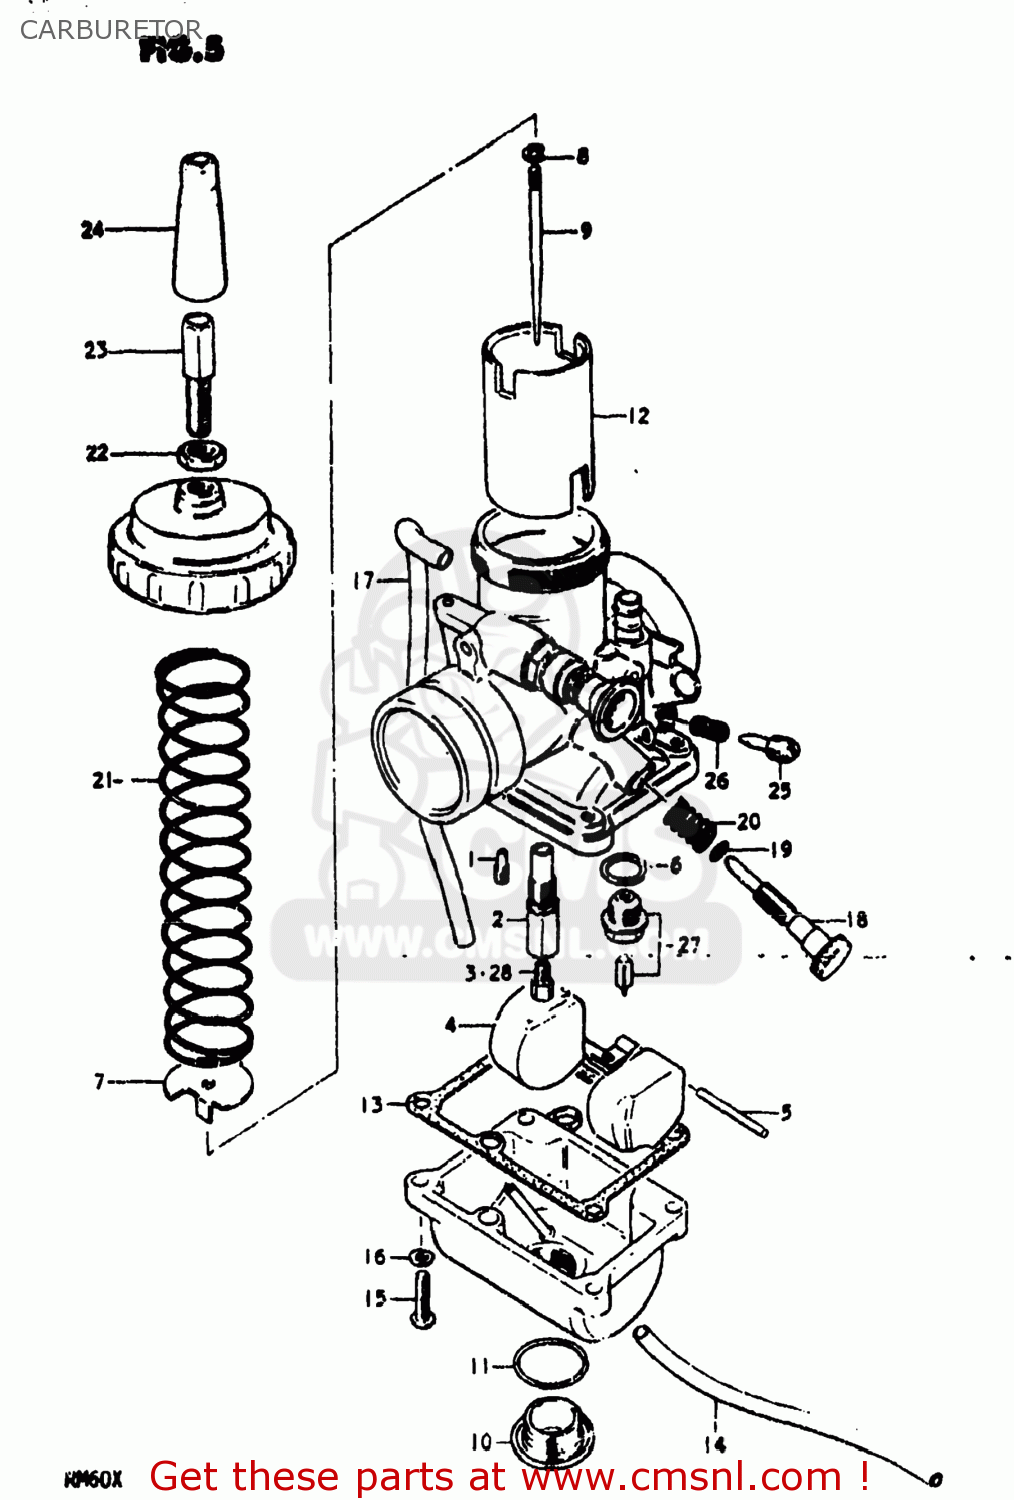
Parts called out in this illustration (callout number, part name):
1	JET,PILOT (17.5)
2	JET,NEEDLE
3	JET
4	FLOAT
5	PIN,FLOAT
6	GASKET,NEEDLE VALVE (NAS)
7	STOPPER,NEEDLE CLIP
8	CLIP
9	NEEDLE JET
10	SCREW,GUIDE
11	O-RING
12	VALVE,THROTTLE
13	GASKET,FLOAT CHAMBER (NAS)
14	HOSE
15	SCREW
16	LOCK WASHER
17	HOSE
18	ADJUSTER
19	O-RING
20	SPRING
21	SPRING,THROTTLE VALVE
22	NUT
23	ADJUSTER,CABLE
24	CAP,CABLE ADJUSTER
25	SCREW,PILOT AIR
26	SPRING
27	VALVE ASSY,NEEDLE
28	JET
